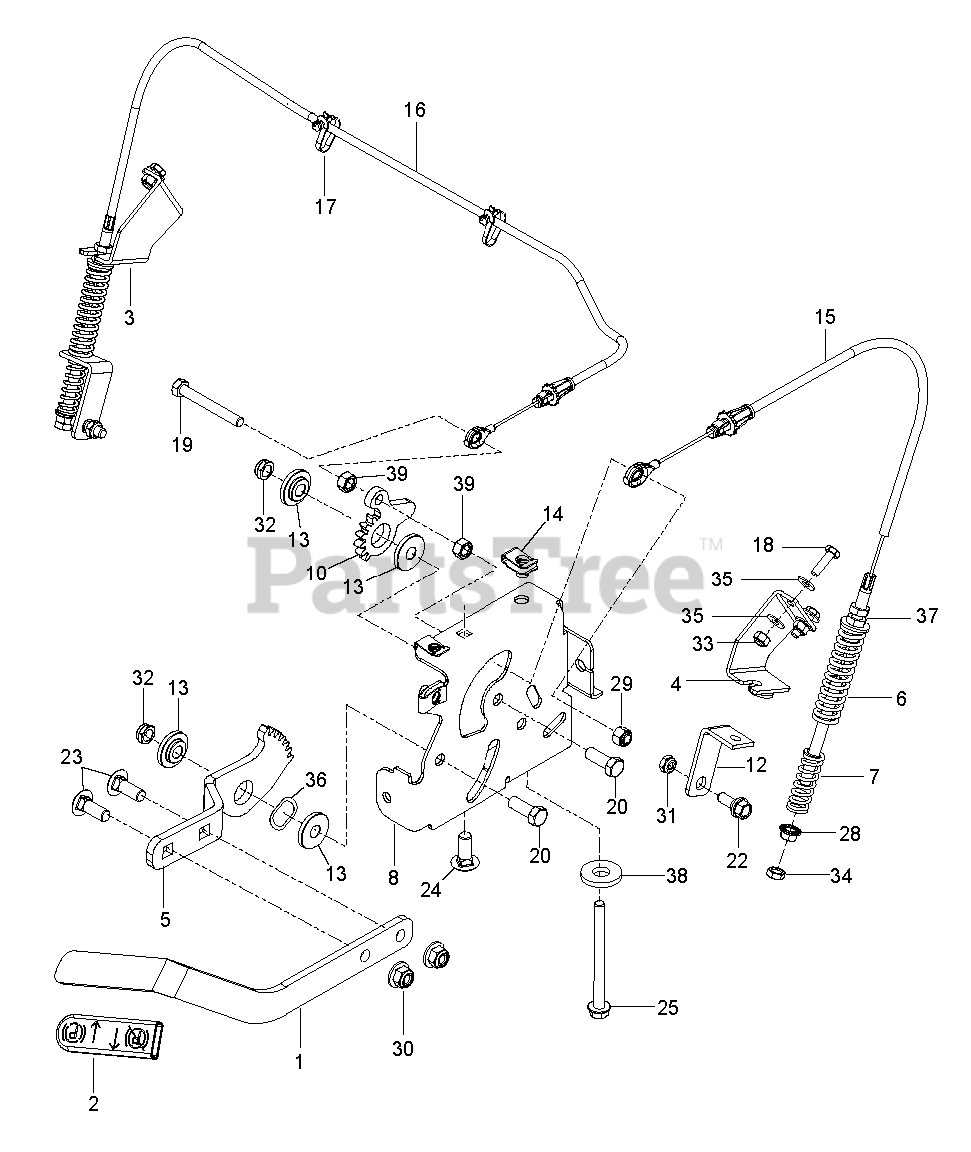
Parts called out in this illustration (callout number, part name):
1	ARM BRAKE BLACK MS-431
2	GRIP, PARK BRAKE
3	BRACKET BRAKE, RT BLACK MS-431
4	BRACKET BRAKE, LT BLACK MS-431
5	GEAR.INPUT.PARKING.BRAKE.MZ
6	SPRING, RETURN
7	SPRING, ENGAGEMENT
8	MOUNT.PNT.BRAKE.MZ.EDIP
10	GEAR OUTPUT;PARKING BRAKE;STAN
12	BRKT, BRAKE, BLK
13	BUSHING, BRAKE
14	U-CLIP 5/16-18 NUT RETAINER
15	CABLE.ASSY.BRAKE.CABLE.SHORT
16	CABLE.ASSY.BRAKE.CABLE.LONG
17	TIE WRAP, 8-3/8", W/CLIP
18	HCS 1/4-20X7/8 GR5
19	HCS 5/16-18 X 2 1/2 TPBLT
20	HCS 3/8-16X1.GRD.5.ZD
22	BOLT, SHOULDER
23	RHSNB 3/8C X 1
24	BOLT 5/16C X 3/4" CARRIAGE
25	HHFS 5/16-18 X 3 3/4
28	NUT 5/16C WHIZ
29	NUT 5/16 NYLOC
30	NUT 3/8-16 HEX FLG NYLOC ZD
31	5/16-18 THIN PROF NY
32	NUT HEX 3/8-16 NYLON, THIN
33	NUT.1/4-20.HEX.NYLOC.ZD
34	NUT 5/16-18 HEX JAM ZD
35	WASHER 1/4 SAE
36	WASHER, .825 X 1.087, WAVE
37	WASHER 3/8 SAE FLAT
38	WASHER.9/16 X 1 3/8 X 12 GA.
39	NUT 5/16C HEX
